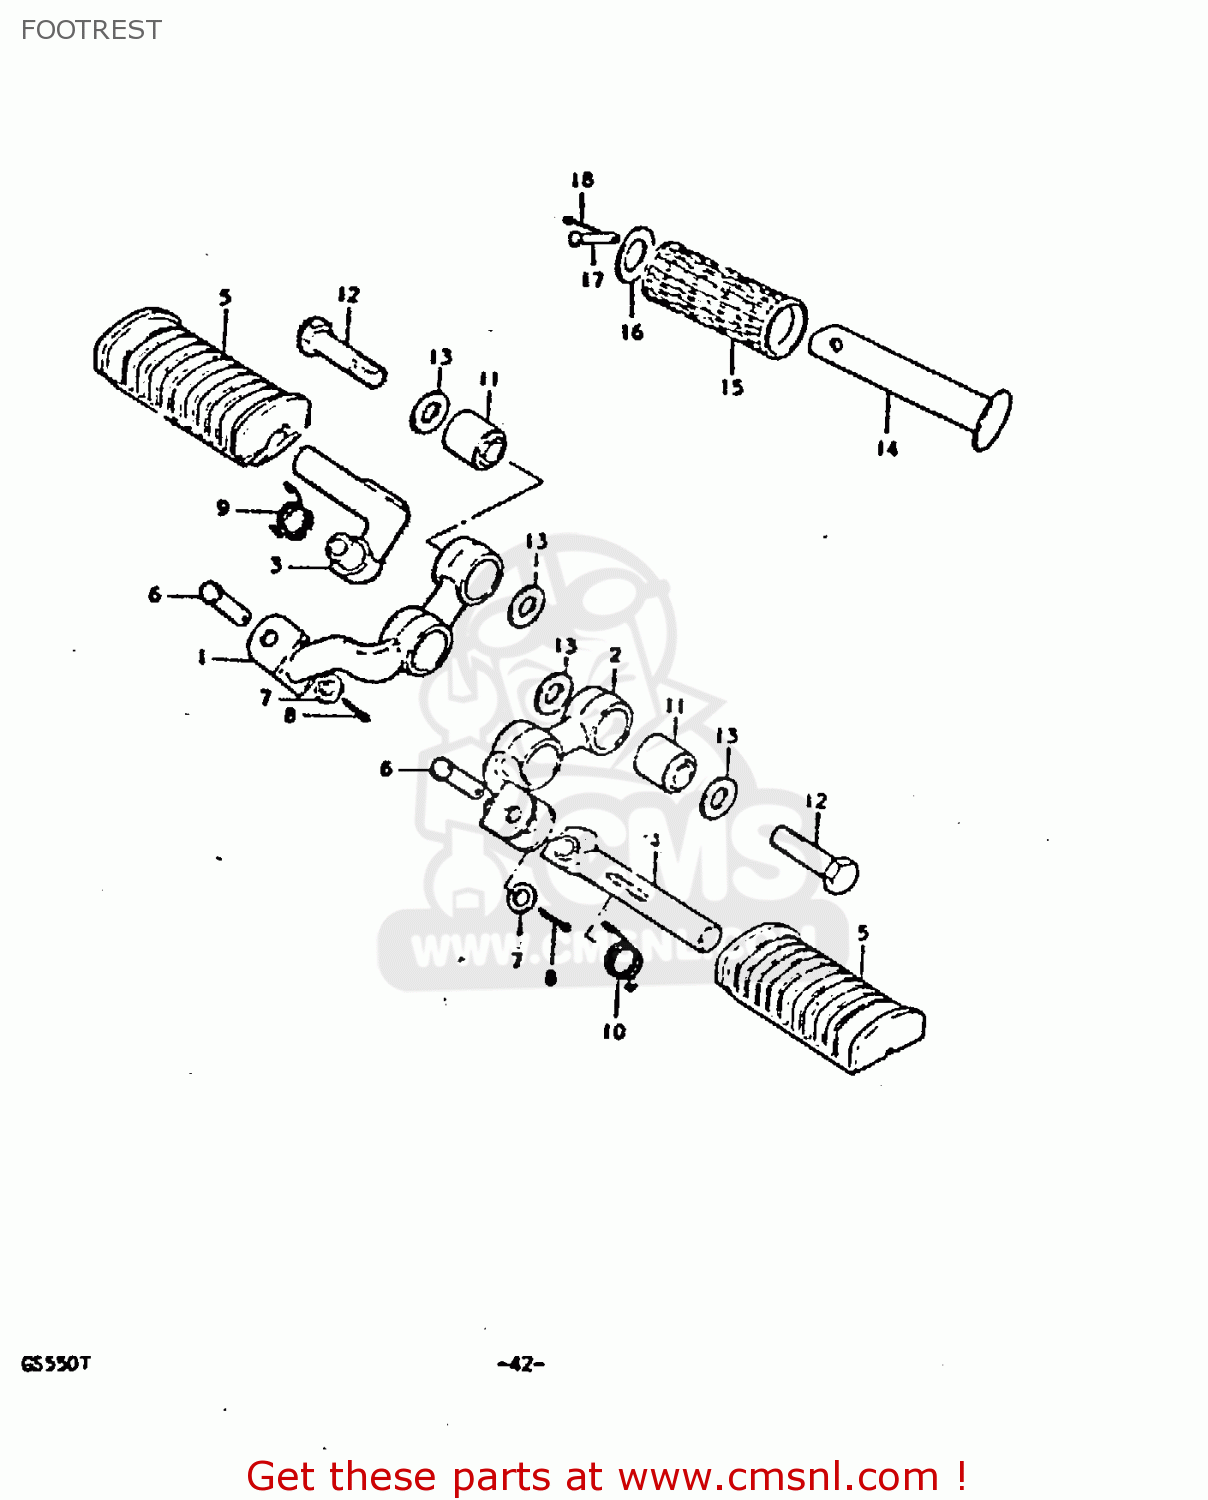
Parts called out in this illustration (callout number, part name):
1	BAR,FRONT FOOTREST,RIGHT
2	BAR,FRONT FOOTREST,LEFT
3	BAR,FRONT FOOTREST,RIGHT NO
4	BAR,FRONT FOOTREST,LEFT NO
5	RUBBER,FR FOOTREST
6	PIN
7	WASHER
8	PIN
9	SPRING
10	SPRING
11	BUSH
12	BOLT
13	WASHER (10.1X21X2.3)
14	BAR,PILLION FOOTREST
15	RUBBER,REAR FOOTREST
16	WASHER (19.5X32X2)
17	PIN
18	PIN
